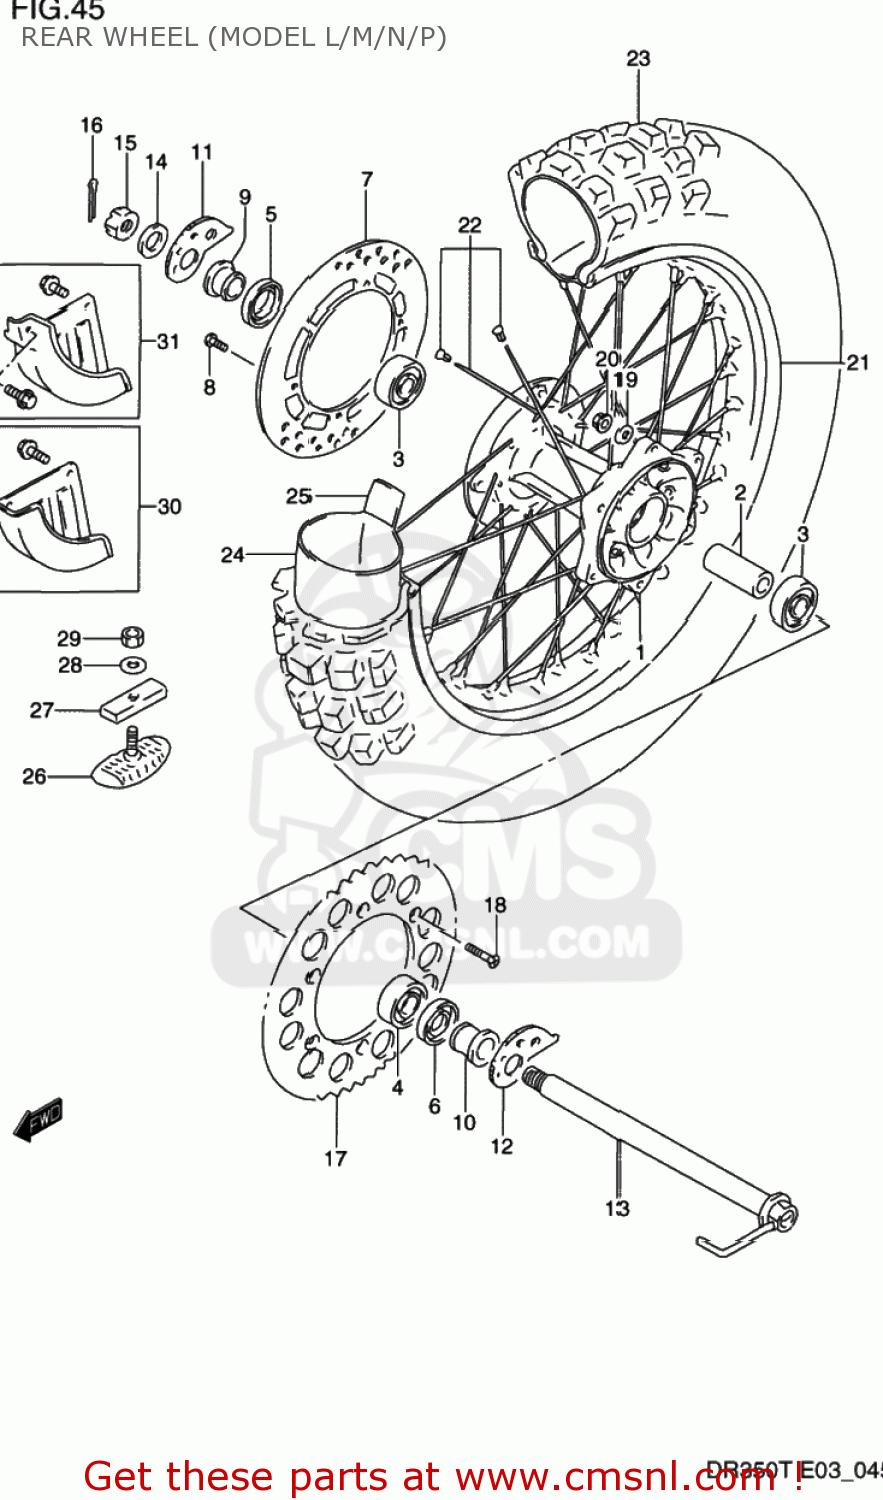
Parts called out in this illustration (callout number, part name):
1	HUB,REAR WHEEL
2	SPACER,RR HUB BEARING
3	BALL BEARING
4	BEARING
5	SEAL,OIL(26X42X8)
6	SEAL,OIL(26X47X5)
7	DISC,RR BRAKE
8	BOLT
9	SPACER,RR AXLE,R
10	SPACER,RR AXLE,L
11	ADJUSTER,CHAIN
12	ADJUSTER,CHAIN,L
13	AXLE,RR
14	WASHER(19X32X3.2)
15	NUT 18MM
16	PIN,COTTER
17	SPROCKET,REAR
18	SCREW(8X33.5)
19	WASHER
20	NUT
21	RIM,RR WHEEL(18X2.15 AL)
22	SPOKE SET,RR WHEEL
23	TIRE COMP,REAR 110/100-1
24	TUBE,INNER
25	PROTECTOR,INNER TUBE
26	STOPPER,BEAD
27	CUSHION,BEAD STOPPER
28	WASHER
29	NUT 8MM
30	COVER SET,REAR BRAKE DRUM
31	COVER SET,RR BRAKE DISC
